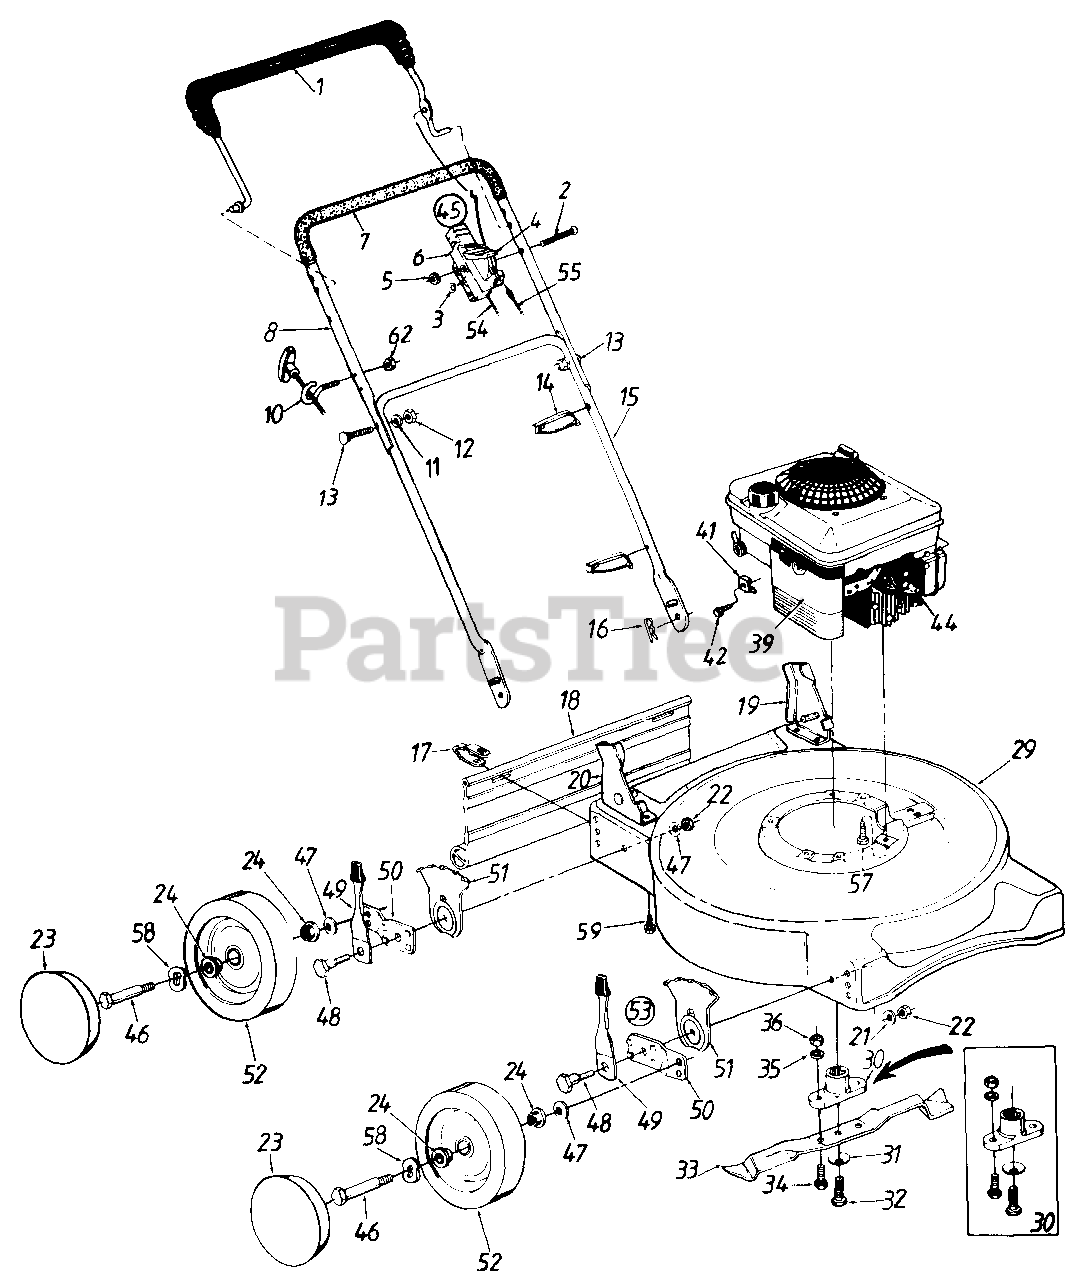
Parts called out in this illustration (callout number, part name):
1	Control Handle Ass'y.
2	Oval C-Sunk Scr.
3	Spr. Wash. .66" I.D.
4	Throttle Lever
5	Hex L-Nut 1/4-20 Thd.
6	Throttle Body
7	Grip
11	L-Wash. 5/16" I.D.
12	Hex Nut 5/16-18 Thd.
13	Curved Carriage Bolt 5/16-18 x 1.38" Lg.
14	Cable Tie
15	Lower Handle
16	Hairpin Cotter
17	Hinge Clip
18	Rear Flap
19	Handle Bracket Ass'y. - L.H.
20	Handle Bracket Ass'y. - R.H.
21	Bell-Wash. .39" I.D. x 1.38"
22	Hex Nut 3/8-16 Thd.
23	Hub Cap
24	Ball Bearing
29	20" Deck Ass'y.
30	Blade Adapter Kit (Keyed)
31	Bell-Wash. .39" I.D. (Keyed)
32	Hex Bolt 7/16-20 x 1.5" Lg. (Keyed)
33	20" Mulching Blade
34	Hex Bolt 3/8-24 x 1" Lg.
35	L-Wash. 3/8" I.D.
36	Hex Nut 3/8-24 Thd.
39	Engine
41	Cable Clamp
42	Hex Self-Tap Scr. #10-32 x .62"
44	Spark Plug Boot
45	Throttle Box Comp.
47	Bell-Wash. .400" I.D. x .88"
48	Shld. Bolt .50" Dia. x .357"
49	Spring Lever Ass'y. w/Knob
51	Height Adj. Plate
52	Wheel Ass'y. Comp.
54	Throttle Cable - 51"
55	Control Cable - 39"
57	Hex L-Wash. Hd. Scr. 3/8-16 x 1.0" Lg.
58	Wave Washer .53" I.D.
59	Hex Wash. Hd. B-Tap Scr. 5/16-18 x .5" Lg.
62	Hex L-Nut 1/4-20 Thr.
